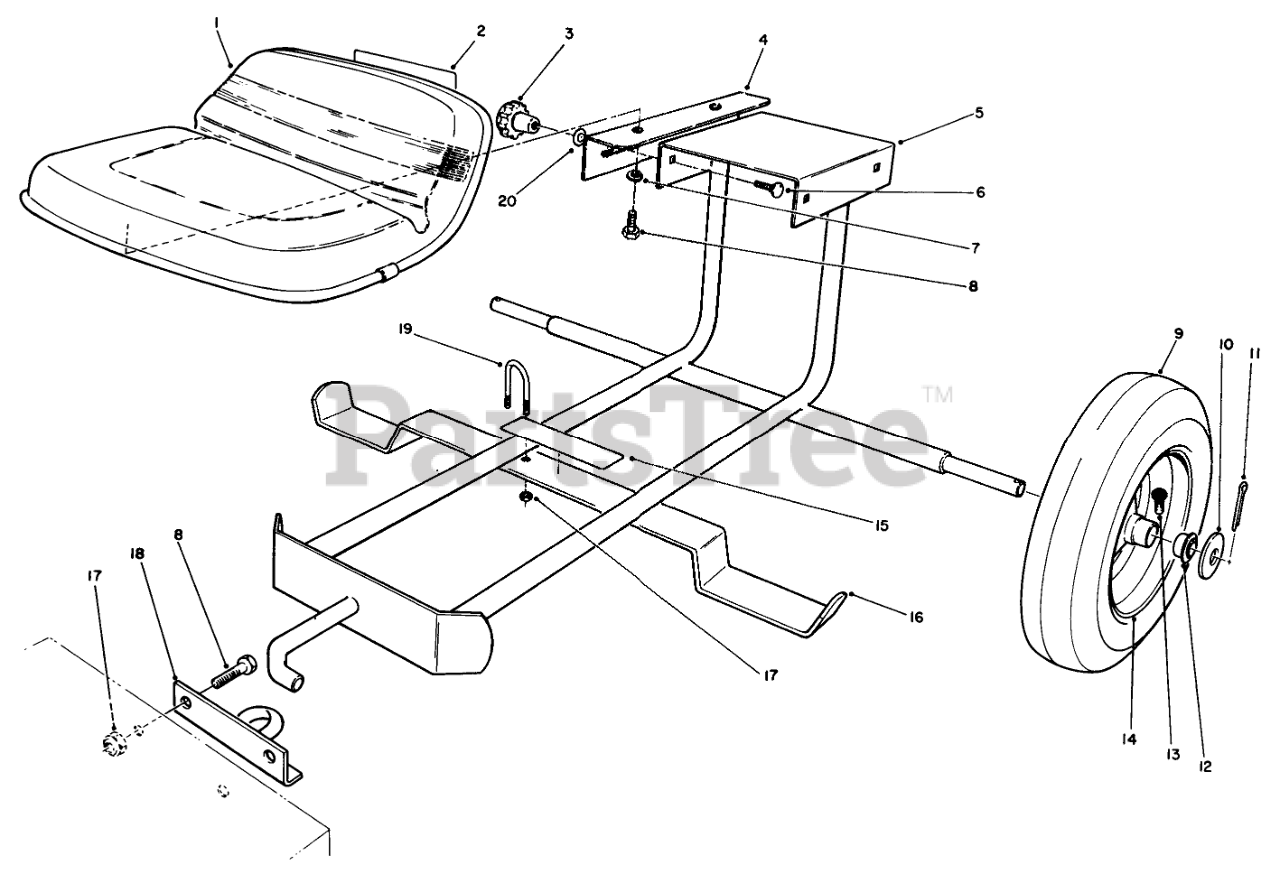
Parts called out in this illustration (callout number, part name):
1	Seat
2	DECAL
4	BRACKET R
5	Frame Assembly
6	BOLT-CARR
7	WASHER-LOCK
8	SCREW-HH
10	WASHER-FLAT
11	PIN-COTTER
12	BEARING
13	VALVE STEM-INNER TUBE
14	WHEEL
15	SULKY DECAL
16	SULKY FOOTREST R
17	NUT-LOCK, NI
18	HITCH
19	U-BOLT
20	WASHER-BELLEVILLE
